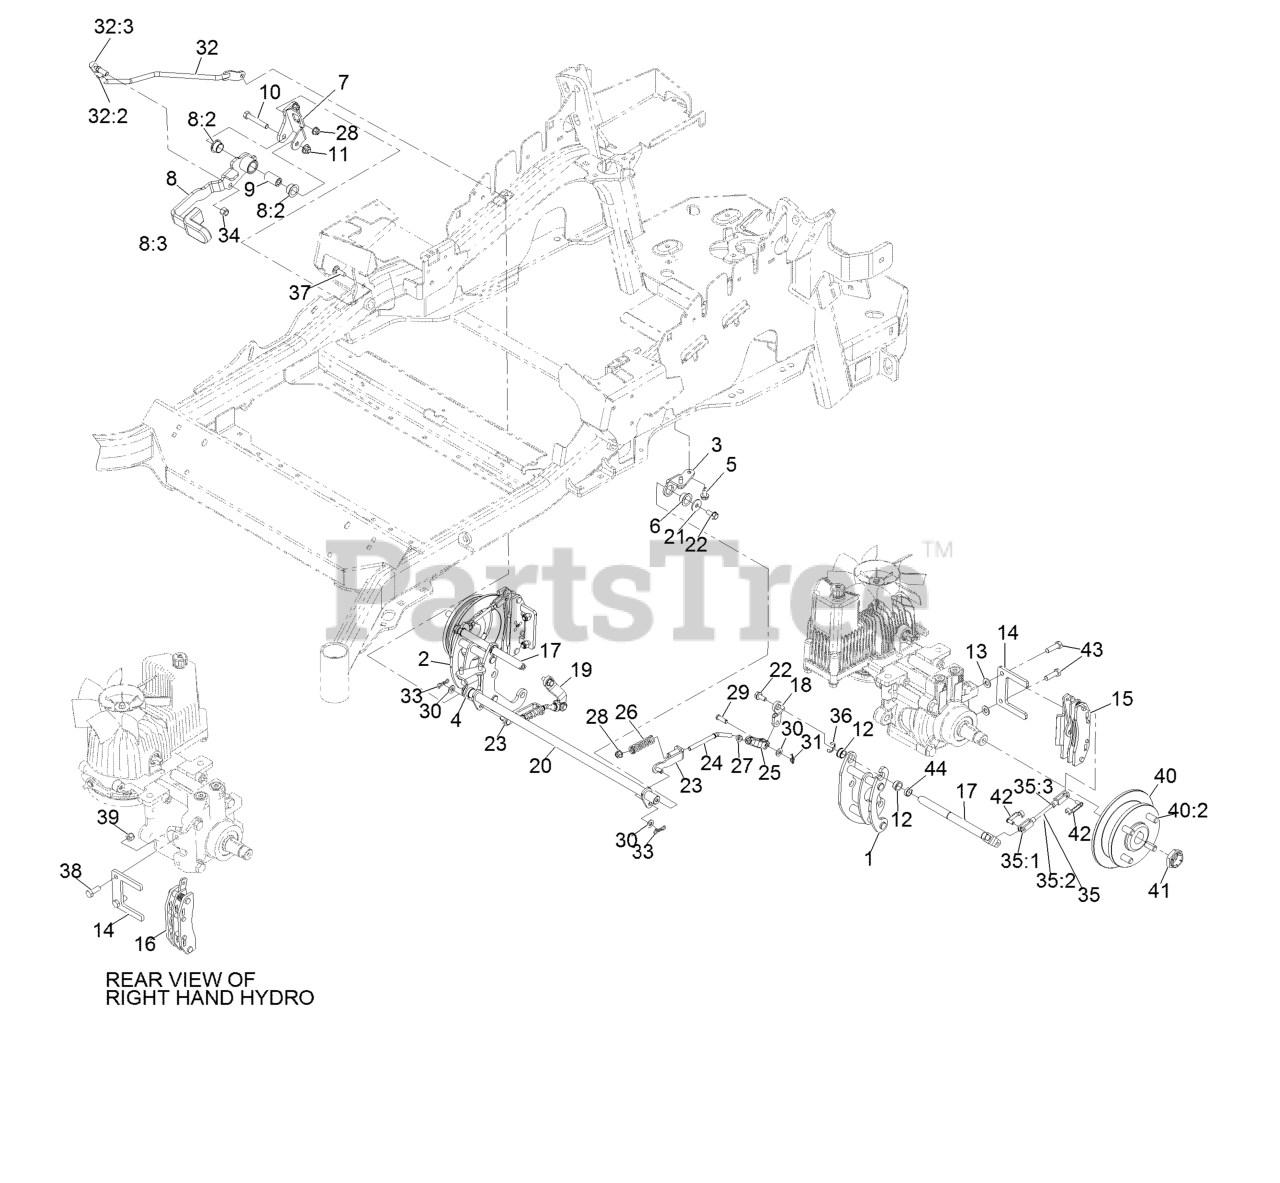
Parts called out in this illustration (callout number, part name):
1	Mount-Bellcrank, LH
2	Mount-Bellcrank, RH
3	Mount-Pivot, LH
4	Mount-Pivot, RH
5	Screw-HWH 5/16-18 X 3/4 Tf
6	Bushing-Flanged
7	Bracket-Mount
8	Brake Lever ASM W/ Grip
8:2	Bushing-Flanged
8:3	Grip-Lever
9	Handle-Pivot, Brake
10	Screw-HH 3/8-16 X 2 1/4
11	Nut-Nyloc 3/8-16 Flg
12	Bushing-Igus
13	Washer-3/8 SAE
14	Plate-Mount, Brake
15	Caliper-Brake
16	Caliper-Brake, RH
17	Bellcrank
18	Arm-Inner, LH
19	Arm-Inner, RH
20	Shaft-Cross
21	Washer-Flat
23	Bracket-L
24	Linkage-Mid
25	Yoke-Offset
26	Spring-Compression
27	Nut-Jam 5/16-24
28	Nut-Nyloc 5/16-18 Flg
29	Pin-Clevis 5/16 X 1 49/64
30	Washer-5/16 SAE
31	Pin-Cotter, Locking
32	Front Linkage ASM
32:2	End-Tie Rod, RH
32:3	Nut-Jam 3/8-24
33	Pin-Cotter, Locking
34	Nut-Nyloc 3/8-24
35	Rear Linkage ASM
35:1	Yoke
35:2	Linkage, Rear
35:3	Nut-Jam 1/4-28
37	Bolt-Carriage 5/16-18 X 1
38	Screw-HH 3/8-16 X 1
39	Nut-Nyloc 3/8-16
40	Wheel Hub ASM
40:2	Stud-Wheel
41	Locknut
42	Pin-Clevis, Spring
43	Screw-HH 3/8-16 X 1 1/4 Patch Lock
